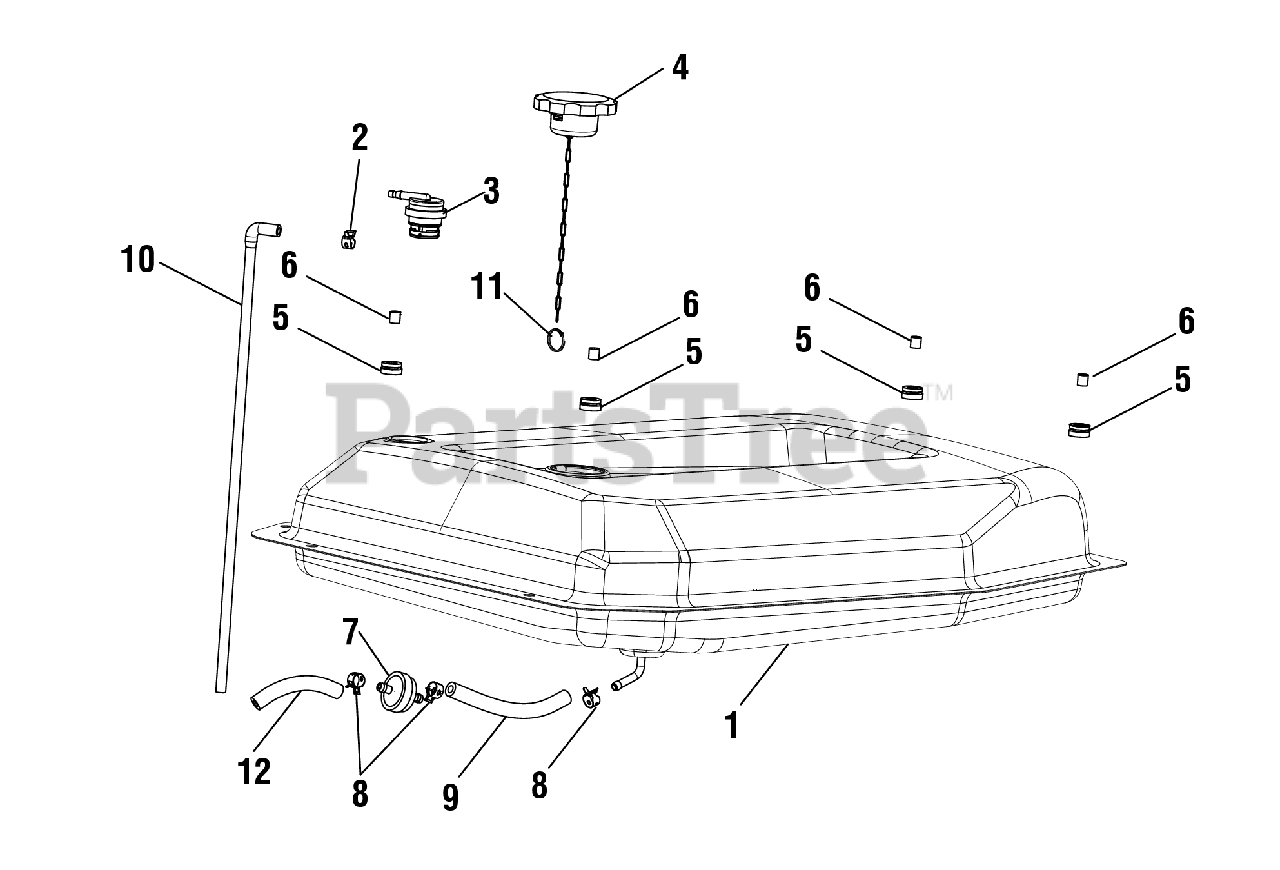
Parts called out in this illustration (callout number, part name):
1	Fuel Tank Assembly (See Fig. B)
2	Fuel Line Clamp (7/16 in., BM903611)
3	Fuel Tank Vapor Vent
4	Fuel Cap Assembly
5	Bushing (Fuel Tank Isolator)
6	Spacer (Fuel Tank Isolator)
7	Fuel Filter Inline (1/4 in.)
8	Fuel Line Clamp (1/2 in.).
9	Fuel Hose (175 mm)
10	Vapor Hose
11	Ring Clip
12	Fuel Hose (85 mm)
